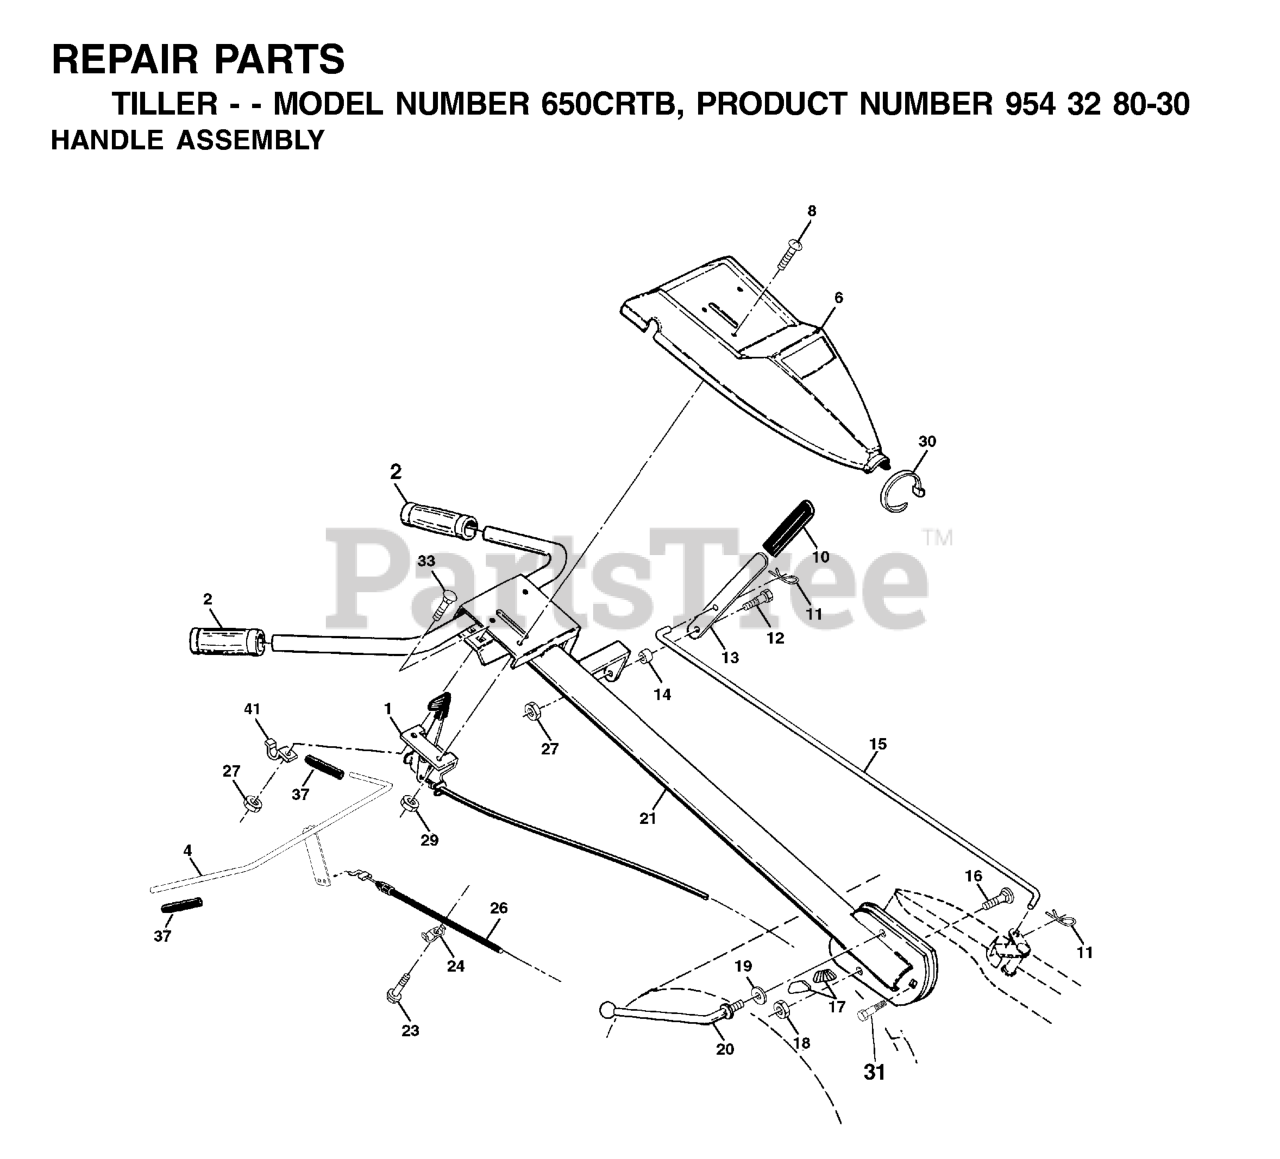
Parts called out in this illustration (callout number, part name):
1	THROTTLE.CONTROL.CRT.TILLER
2	KIT.GRIP.HANDLE.5.00.BLK.VINYL
4	CONTROL BAR ASSY
6	RP CONTROL PANEL
8	SCREW.PNHD.10-24
10	GRIP T
11	RETAINER M
12	SHOULDER BOLT ST
13	SHIFT HANDLE CRT
14	GROMMET.RUBBER.CRT.TILLER
15	SHIFT ROD CRT
16	BOLT D
17	LOCK.HANDLE.CRT
19	WASHER CRT
20	LEVER.LOCK.CRT
21	REPL BY 532 1805-17
23	TAPPING SCREW
24	CONDUIT.CLIP.PLATED
26	CABLE.CLUTCH
27	NUT T
29	NUT **
30	TIE CABLE CRT
31	BOLT.PIVOT
33	BOLT
37	GRIP BAR CRT(1)
41	CLAMP.BAR.CRT.BLACK
